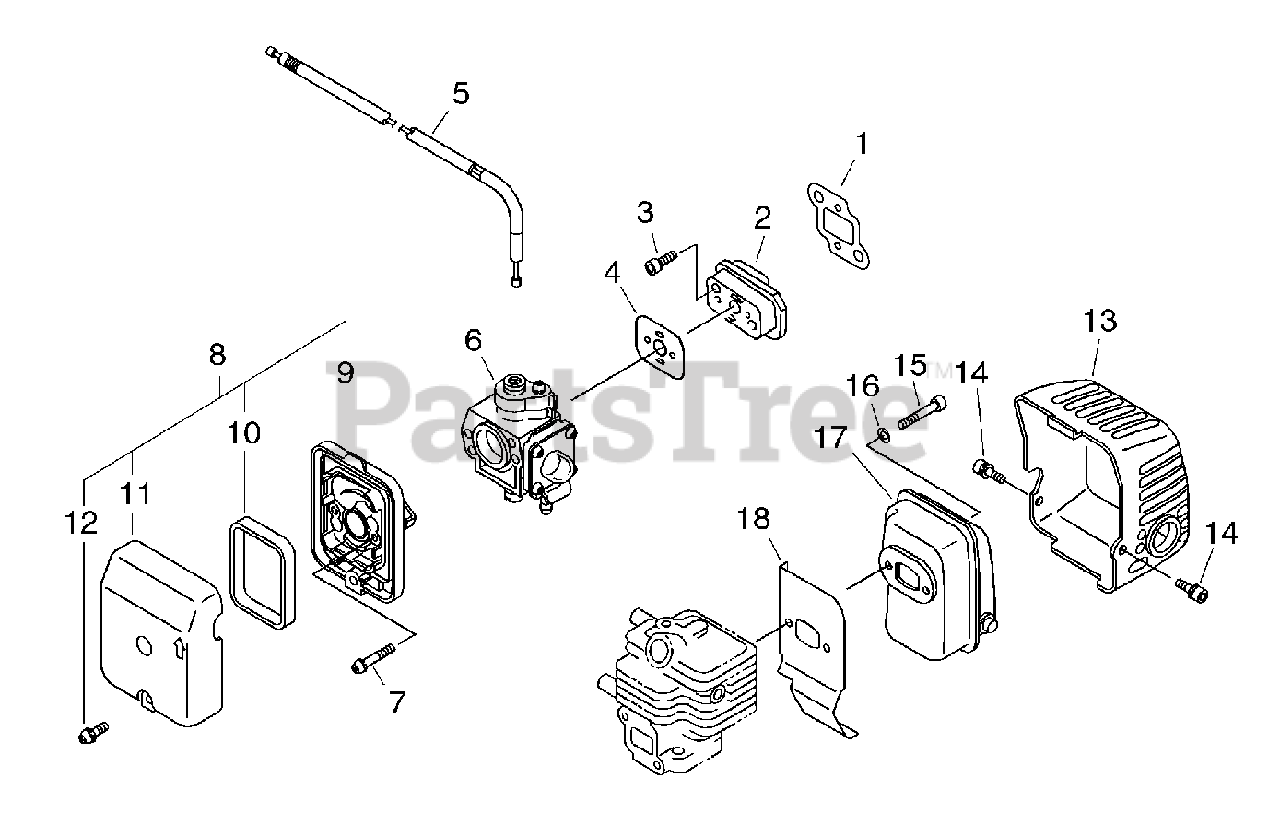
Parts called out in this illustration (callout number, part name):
1	Gasket, Intake
2	Insulator
3	Bolt, H.s. 5x25
4	Gasket, Intake
5	Throttle Wire
6	Carburetor
7	Screw 5x50
8	Cleaner Asm., Air
9	Case, Air Cleaner
10	Filter, Air
11	Cover, Air Cleaner
13	Cover, Muffler
14	Bolt, H.s. 5x8
15	Bolt, H.s. 5x55
16	Washer 5
18	Gasket, Muffler
